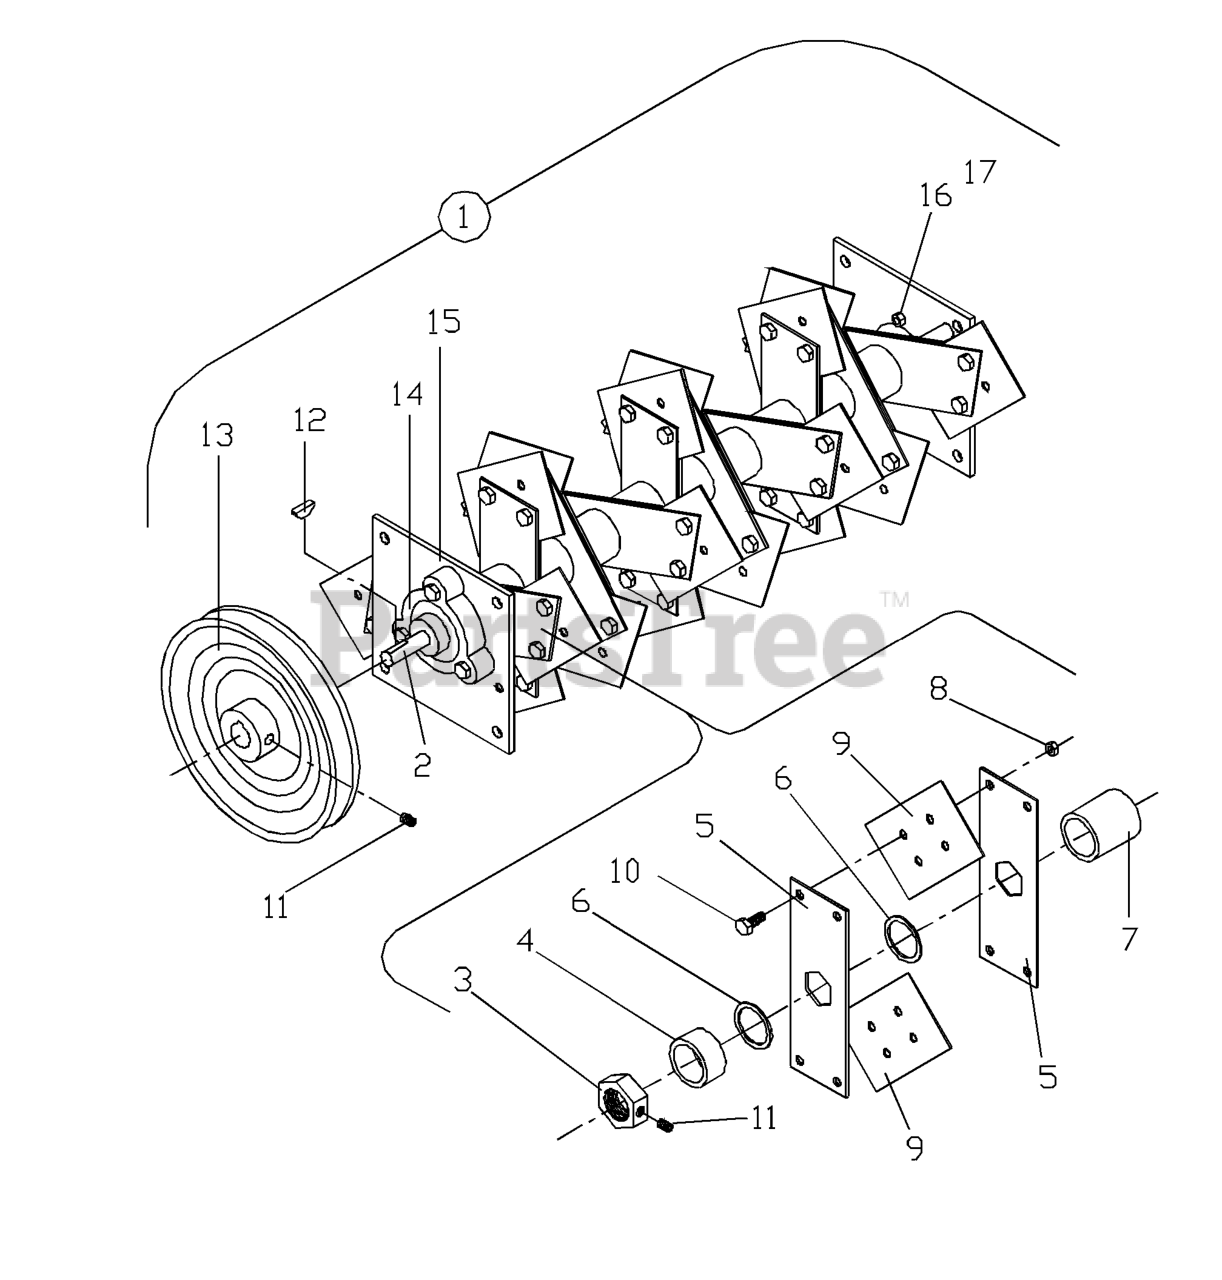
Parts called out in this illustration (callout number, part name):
1	SLICER SHAFT, QUICK CHANGE
2	SLICER SHAFT
3	JAM NUT W/SET SCREW
4	SLEEVE SPACER, SHORT
5	BLADE HOLDER PLATE
6	BLADE WASHER
7	SLEEVE SPACER, LONG
8	1/4-20 NYLOC NUT
9	SLICER BLADE
10	1/4-20 X 5/8 HCS
11	5/16-18 X 3/8 SET SCREW
12	#9 WOODRUFF KEY
13	MAIN SHAFT PULLEY
14	FLANGED BEARING
16	5/16-18 X 1-1/4 TAP BOLT
17	5/16-18 NYLOC NUT
